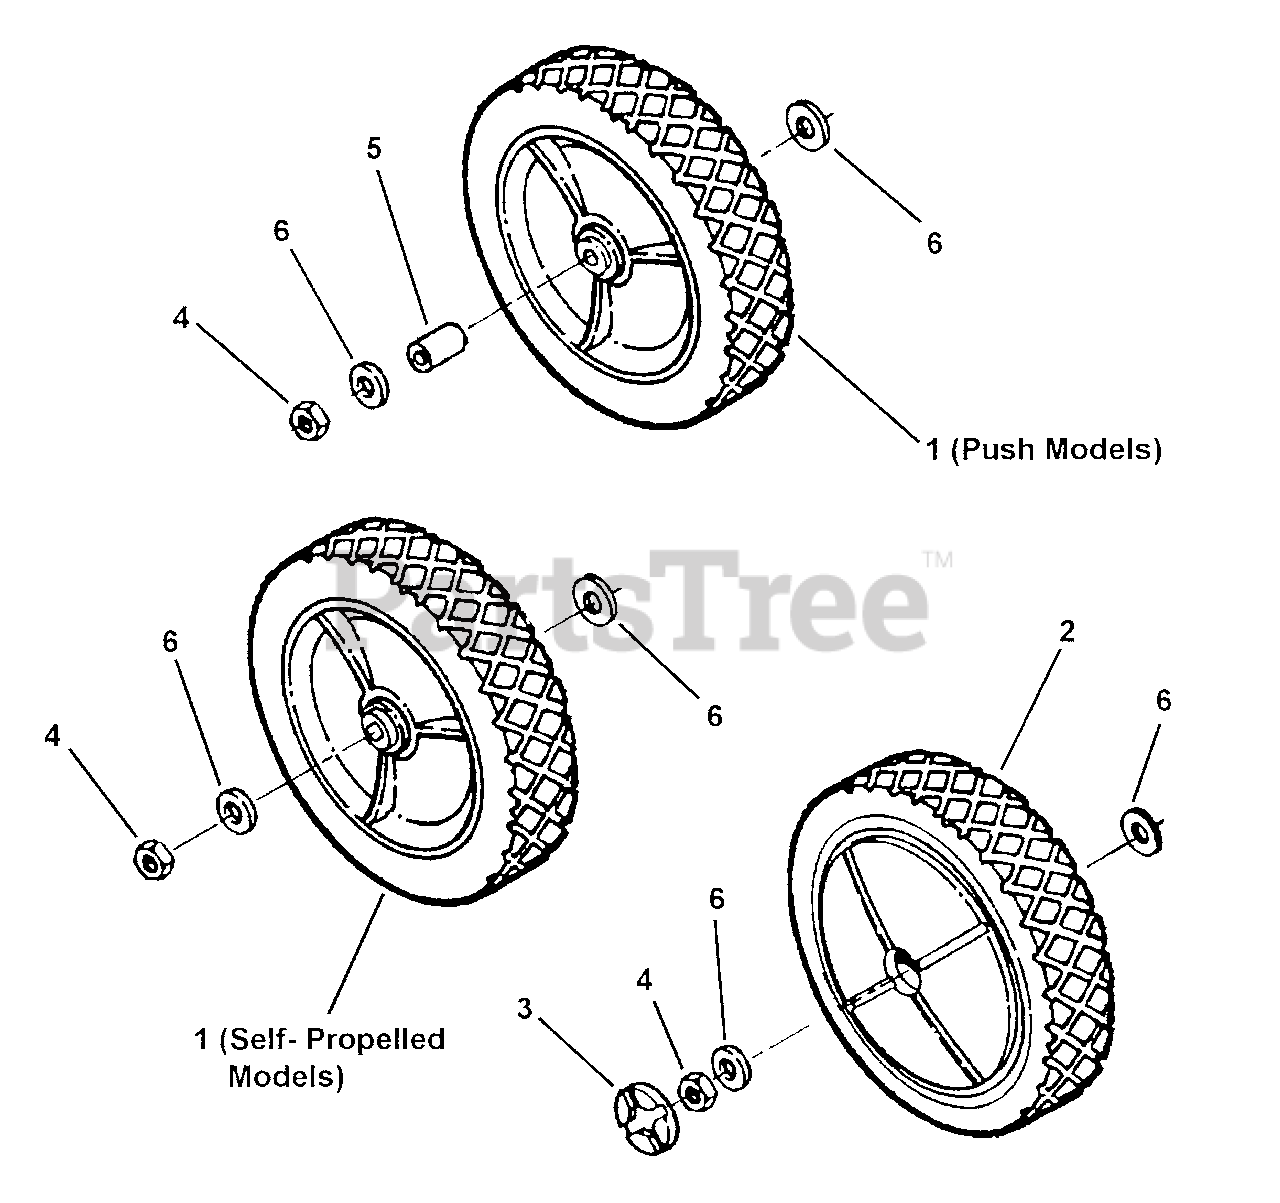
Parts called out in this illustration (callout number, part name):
1	WHEEL, 10 x 1.75 Plastic
2	WHEEL, 10 x 1.75 Plastic
3	PLUG, Wheel
4	NUT, 7/16-20 Hex (Thin)
5	BUSHING, Axle
6	WASHER, 7/16 x 1" O.D. Flat
